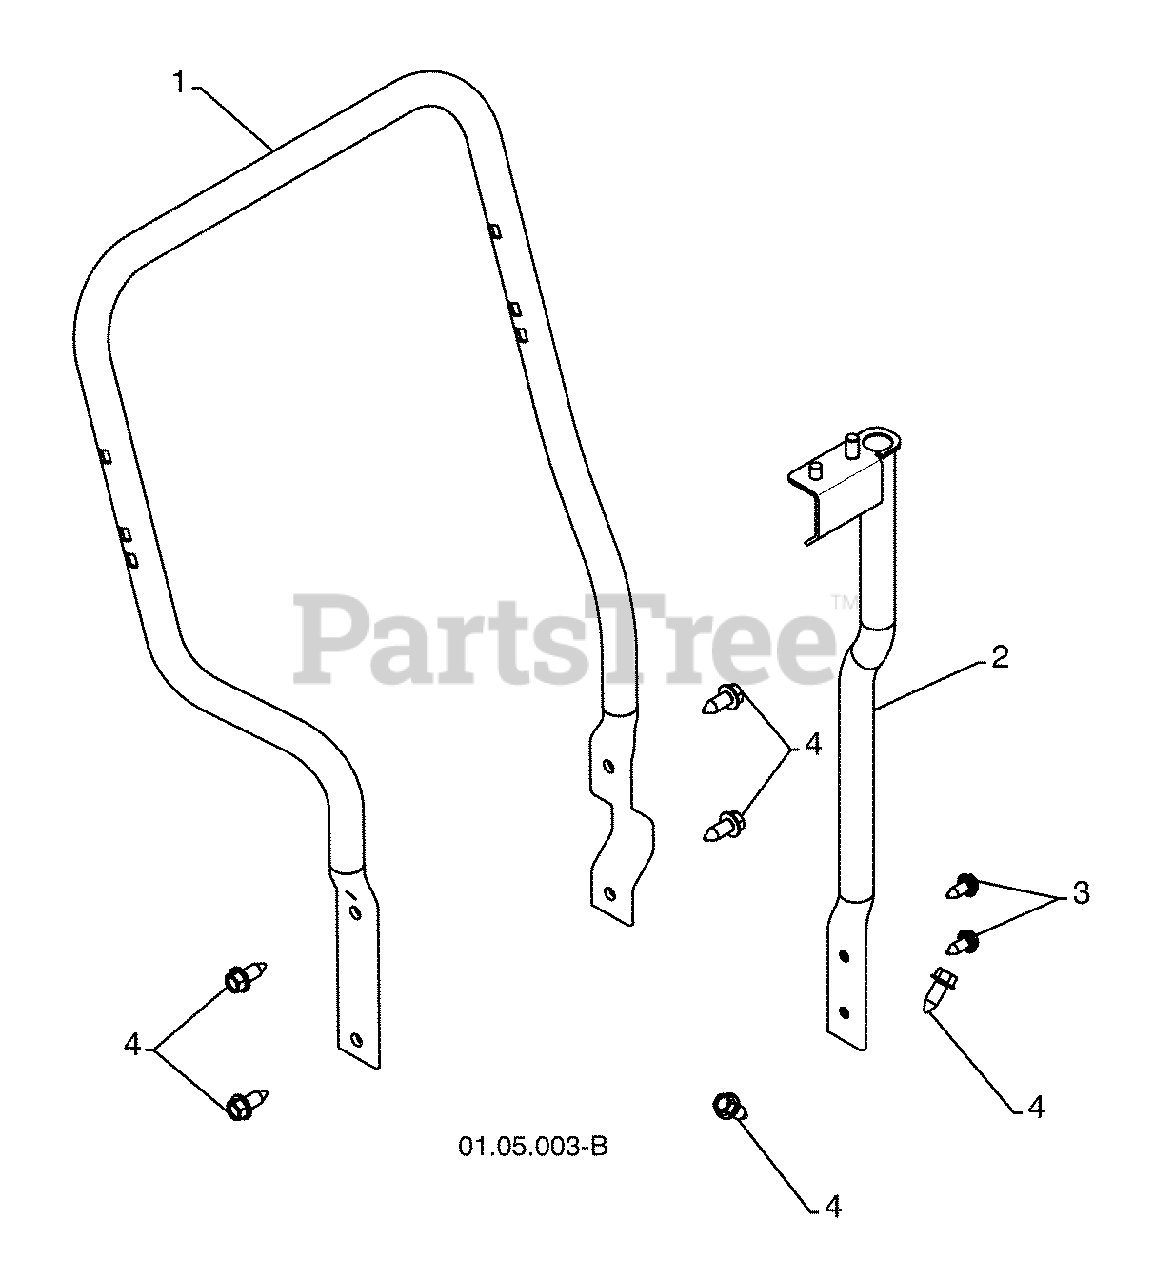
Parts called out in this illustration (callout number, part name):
1	LOWER TUBE
2	PIVOT SUPPORT
3	BOLT 5/16--18 X .750
4	SCREW 3/8--16 X 1.00
